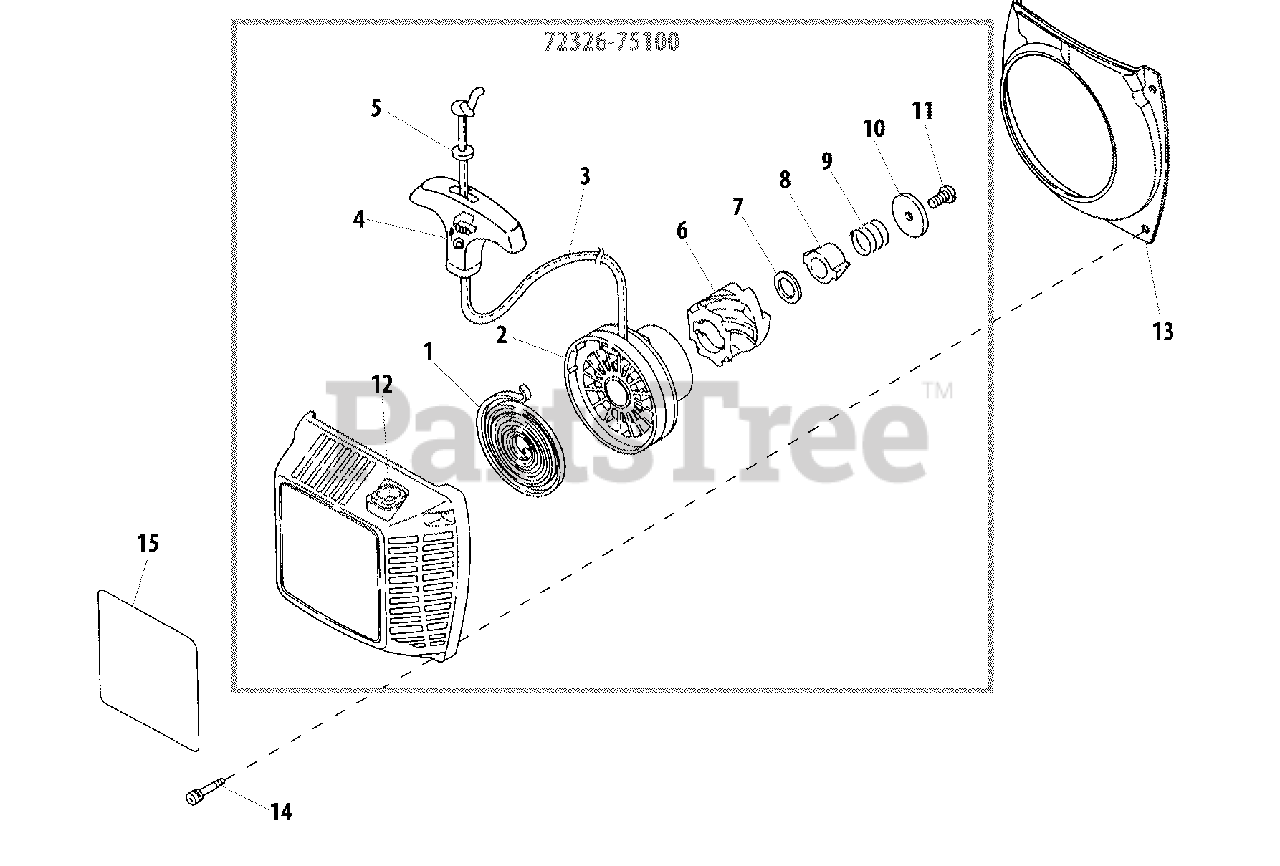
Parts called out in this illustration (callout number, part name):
1	SPRING, RECOIL
2	REEL, ROPE
3	ROPE, STARTER
4	GRIP, STARTER
5	RETAINER, ROPE
6	RATCHET
7	WASHER, THRUST
8	PAWL CATCHER
9	SPRING, FRICTION
10	WASHER
11	SCREW 5
12	GUIDE, ROPE
13	PLATE, AIR
14	BOLT M4×20
15	LABEL - MODEL
72326-75101	STARTER ASSY, RECOIL
